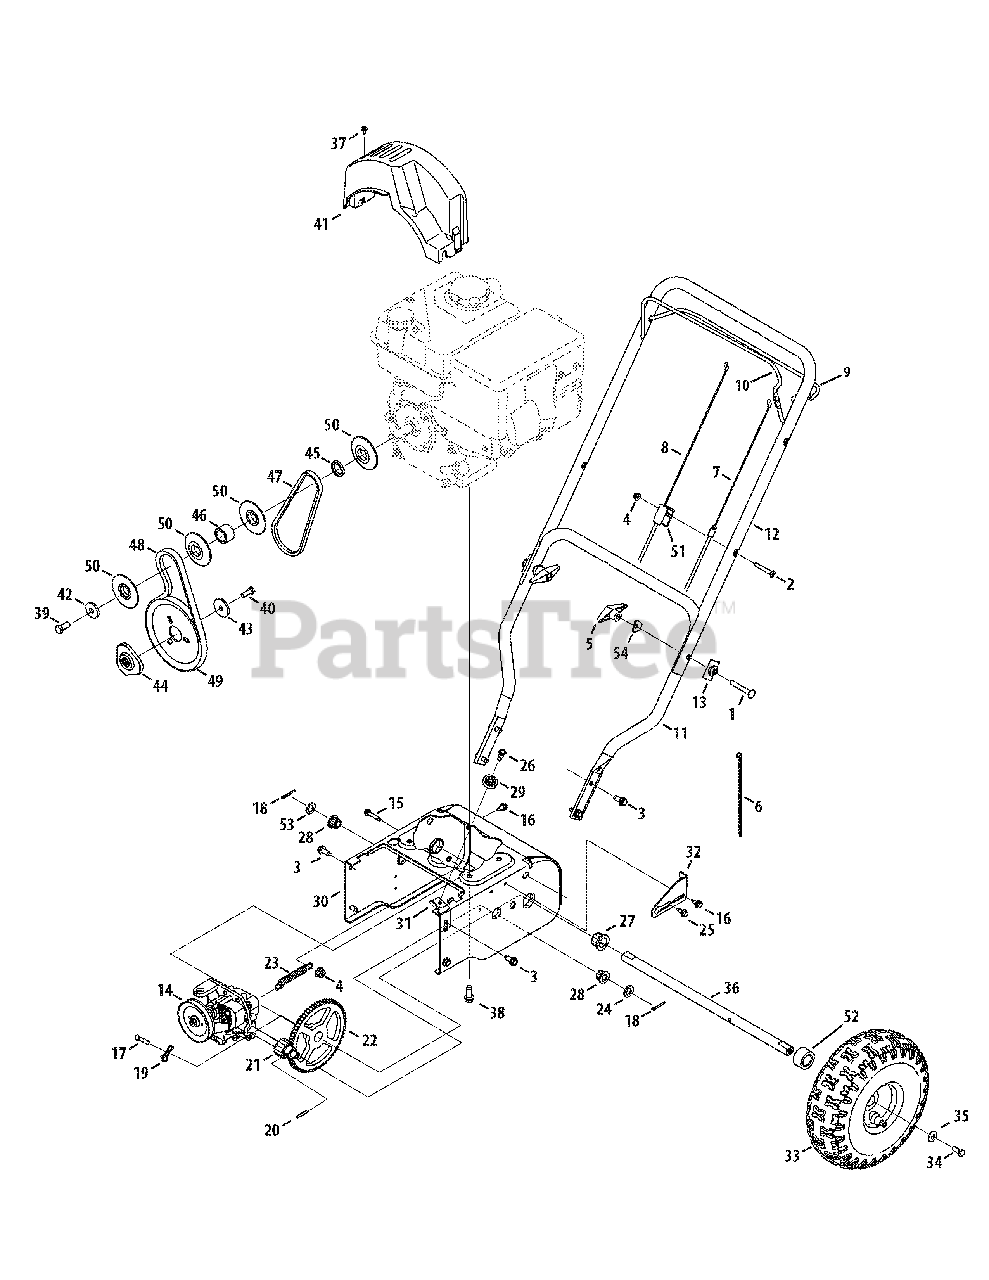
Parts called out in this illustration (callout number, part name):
1	Carriage Screw 5/16-18 x 2.25
2	Mach. Screw 1/4-20 x 1.825
3	Screw 5/16-18 x .75
4	Flange Lock Nut 1/4-20
5	Wing Knob 5/16-18
6	Cable Tie
7	Drive Cable
8	Auger Cable
8	Fitting, Dual Cable
9	Auger Control
10	Drive Control
12	Upper Handle
13	Handle Tab
14	Transmission Assembly
15	Self-Tapping Screw 1/4-20 x 1.25
16	Screw 1/4-20 x .625
17	Clevis Pin
18	Cotter Pin 1/8 x 1.0
19	Bow Tie Cotter Pin 72
20	Roll Pin
21	Pinion 14T
22	Gear 70T
23	Extension Spring
24	Flat Washer
25	Shoulder Screw 1/4-20
26	Shoulder Screw 1/4-28
27	Hex Flange Bearing
28	Hex Flange Bearing
29	Cable Roller
30	Drive Housing Frame - Red
30	Drive Housing Frame - Black
30	Drive Housing Frame - Green
31	Auger Cable Bracket
33	Wheel Assy. Snow Hog Gray
33	Tube, Tire, 4.10/3.50-4.0
34	Lock Bolt 5/16-24 x .75
35	Bell Washer .34 x .872 x .06
37	Hex Screw #10-16 x .500
38	Sems Screw 3/8-16 x 1.0
39	Hex Bolt 3/8-24 x .875
40	Lock Bolt 5/16-24 x .875
41	Belt Cover
42	Flat Washer .406 ID x 1.25 OD
43	Flat Washer .34 ID x 1.50 OD
44	Pulley: Adapter .75 Dia.
45	Spacer .876 x 1.25 x .19
46	Spacer .876 x 1.25 x .86
47	V-belt 3/8 x 21.108 Lg.
48	V-belt 3/8 x 26.375 Lg.
49	Auger Pulley
50	Pulley Half
51	Cable Clip
53	Flat Washer .53 x .93 x .05
54	Saddle Washer
